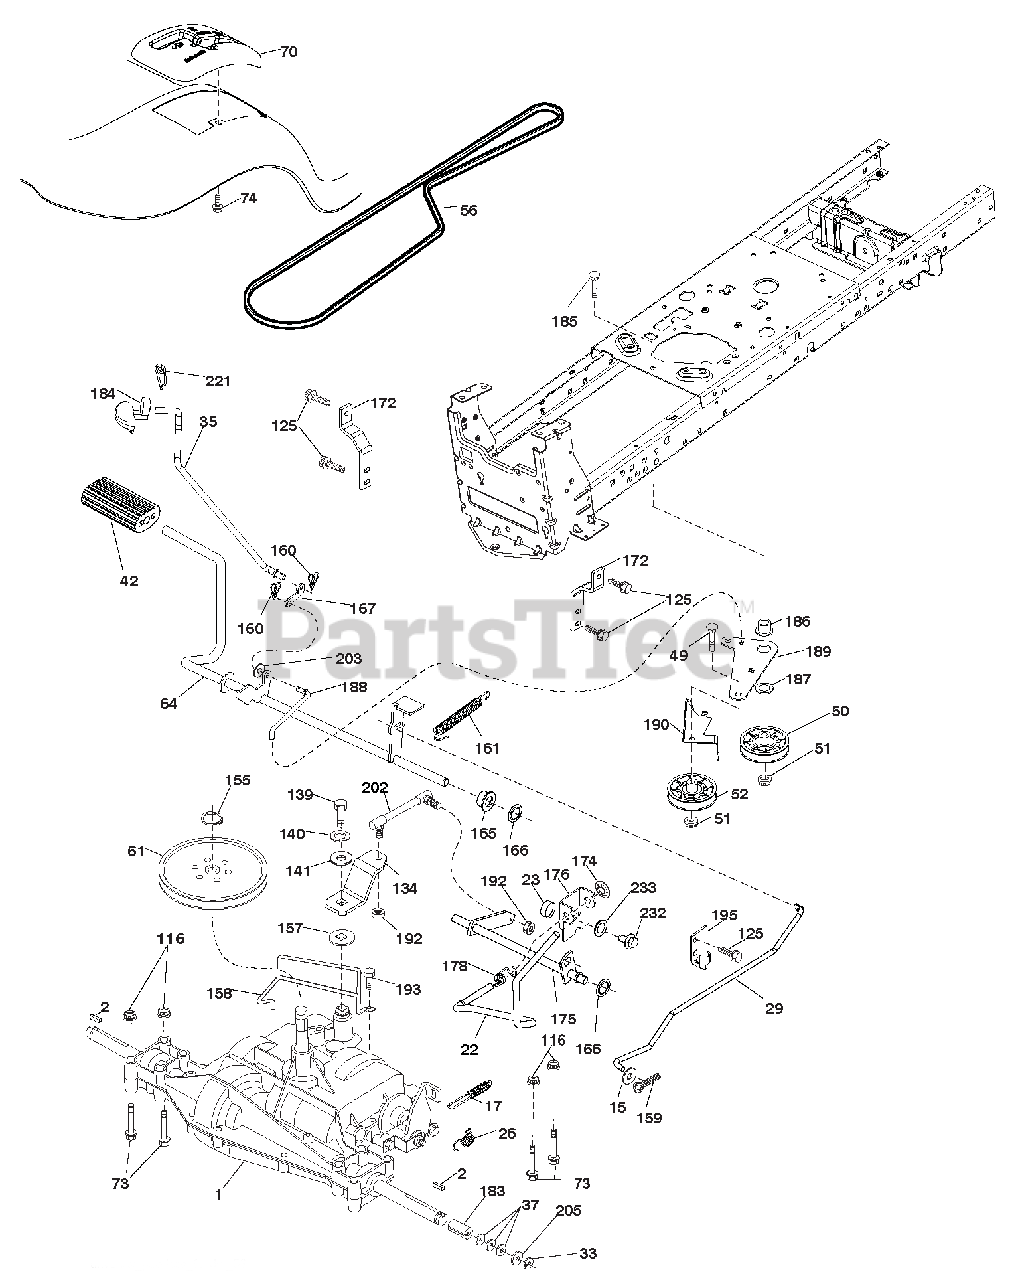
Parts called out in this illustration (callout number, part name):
2	KEY.SQUARE.2.0 X .1845/.1865
15	WASHER.13/32 X 13/16 X 16 GA.
17	SPRING.BRAKE.PEERLESS/D6800.TX
22	ROD.SHIFT.FENDER.TLT.2006
26	SPRING.BRAKE.RTN.GR DR.TEX.006
29	ROD.BRAKE.PEERLESS/D6800
33	E-RING.#5133-75
35	ROD, BRAKE, PARK
37	WASHER.25/32 X 1 1/4 X 16 GA.
42	COVER PEDAL BLK ROUND
49	BOLT.RDHD.3/8-16UNCX1-3/4.GR5
50	IDLER.FLAT.910"OFFSET
51	Nut, Hex, Flangelock 3/8-16
52	IDLER.V-GROOVE.910"OFFSET
56	V-BELT.DRV.97.40"PMST/DANA
61	PULLEY.TRANSAXLE.18/20"TIRES
64	SHAFT ASM.PEDAL.BRAKE CONTROL
70	CONSOLE SHIFT
73	BOLT 5/16-18 X 2 1/2 G.5
74	SCREW.HEX.WSH.HI-LO.1/4X1/2UNC
116	Nut, Lock Hex Flange 5/16-18 u
125	SCREW.5/16-18X3/4.SMGML.TAP/BL
134	ASM SHIFT
139	BOLT.1/4-28 UNF.GR8.W/PATCH
140	Washer, Lock 1/4
141	WASHER.9/32 X 3/4 X 10 GA.
155	Ring, Retainer
157	WASHER.PLATE.SHF..388 SQ.HOLE
158	KEEPER.T/A.PMS/D4360/D680.1820
159	PIN.COTTER.1/8 X 3/4.CAD.
160	RETAINER.CLIP(M).DIA.290
161	SPRING.RETURN.CLUTCH.6.75
165	BUSHING.SHAFT.BRAKE.HAND CONTR
166	NUT PUSH .625
167	LATCH.BRAKE.PARKING
172	STRAP.TRQ.LH.GEAR DRIVE.LT.TEX
174	NUT.PUSH..500
175	SHAFT ASM. SHIFT GEAR DRIVE
176	ARM.CLEVIS.ROD.SHIFT
178	SPRING.SHIFT.GT.2006
183	SPACER.AXLE.HYDRO/PEERLES
184	HANDLE PARKING BRAKE
185	BOLT.RDHD.3/8-16UNC X2-3/4 GR5
186	SPACER.RETAINER
187	WASHER.13/32 X 2 X 10 GA.
188	LINK.CLUTCH.GROUND DRIVE
189	BELLCRANK.GROUNDRIVE.NSTG/NSTL
190	KEEPER.BELLCRANK.DRIVE.GROUND
192	NUT.LOCK.CENTER.1/4-28 FNTHD.
193	SCREW.5/16-18X3/4.SMGML.TAP/R
195	BRACKET.ROD.BRK.PEERLESS/D6800
203	Washer 11/32 x 11/16 x 16 Ga.
205	WASHER.25/32 X 1-5/8 X 16GA.
221	RETAINER.SPRING.CLIP.HANDLE
232	BOLT.FIN HEX.7/16-14X1 GR5
233	WASHER.SERRATED
